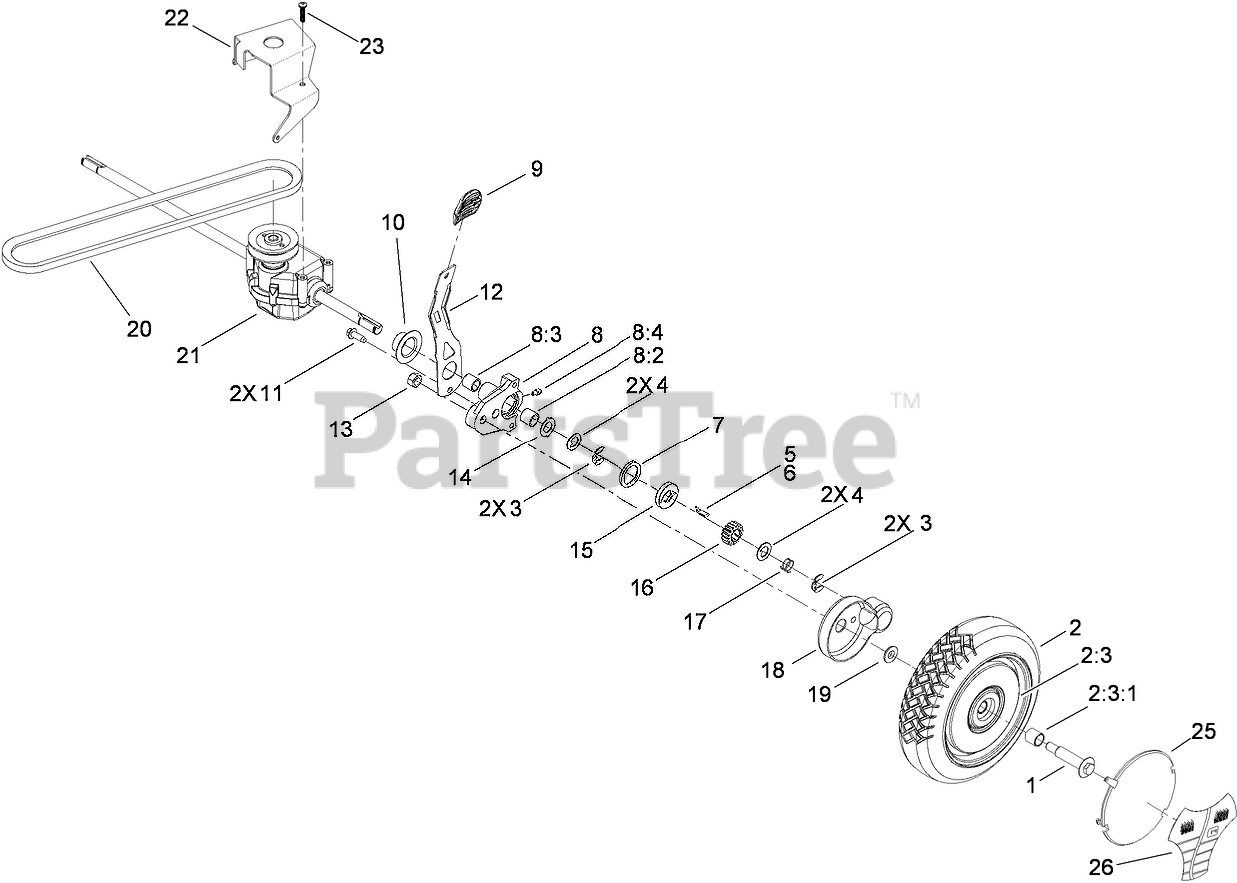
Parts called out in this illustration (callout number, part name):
1	BOLT-SHOULDER
2	WHEEL AND TIRE ASM (WITH GEAR)
2:3	WHEEL AND TIRE ASM
2:3:1	BUSHING
3	RING-CLIP, LOCKING
4	WASHER-THRUST, KEYED
6	KEY-ROCKING, LH
7	RING-FRICTION
8	PIVOT ARM ASM
8:2	BUSHING
8:3	BUSHING
8:4	FITTING-GREASE
9	Knob-Lever, HOC
10	CAP-END
11	SCREW-HWHTF
12	ARM-SPRING
14	WASHER-ARM, PIVOT
15	WASHER-CLUTCH
16	GEAR-PINION
17	SPRING-COMPRESSION
18	COVER-WHEEL
19	SPACER-COVER, WHEEL
20	V-BELT
21	TRANSMISSION ASM
22	BRACKET-TRANSMISSION
23	SCREW-PLASTITE
25	COVER-WHEEL
26	LABEL-WHEEL, SMART
